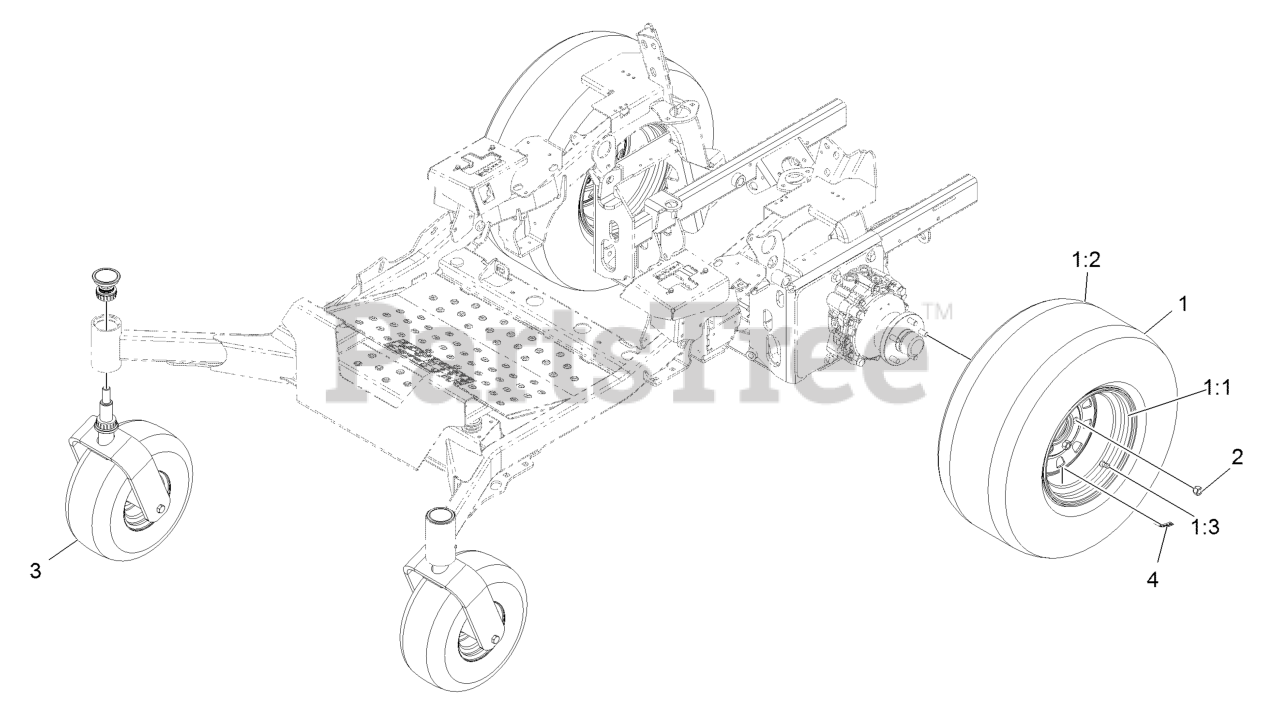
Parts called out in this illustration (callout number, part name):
1	ASM-Tire 26 X 12-12
1:1	Rim ASM
1:3	Stem-Valve
2	Nut-Lug 1/2-20
3	ASM, Wheel Caster
4	Decal-Torque, Wheel Nut
